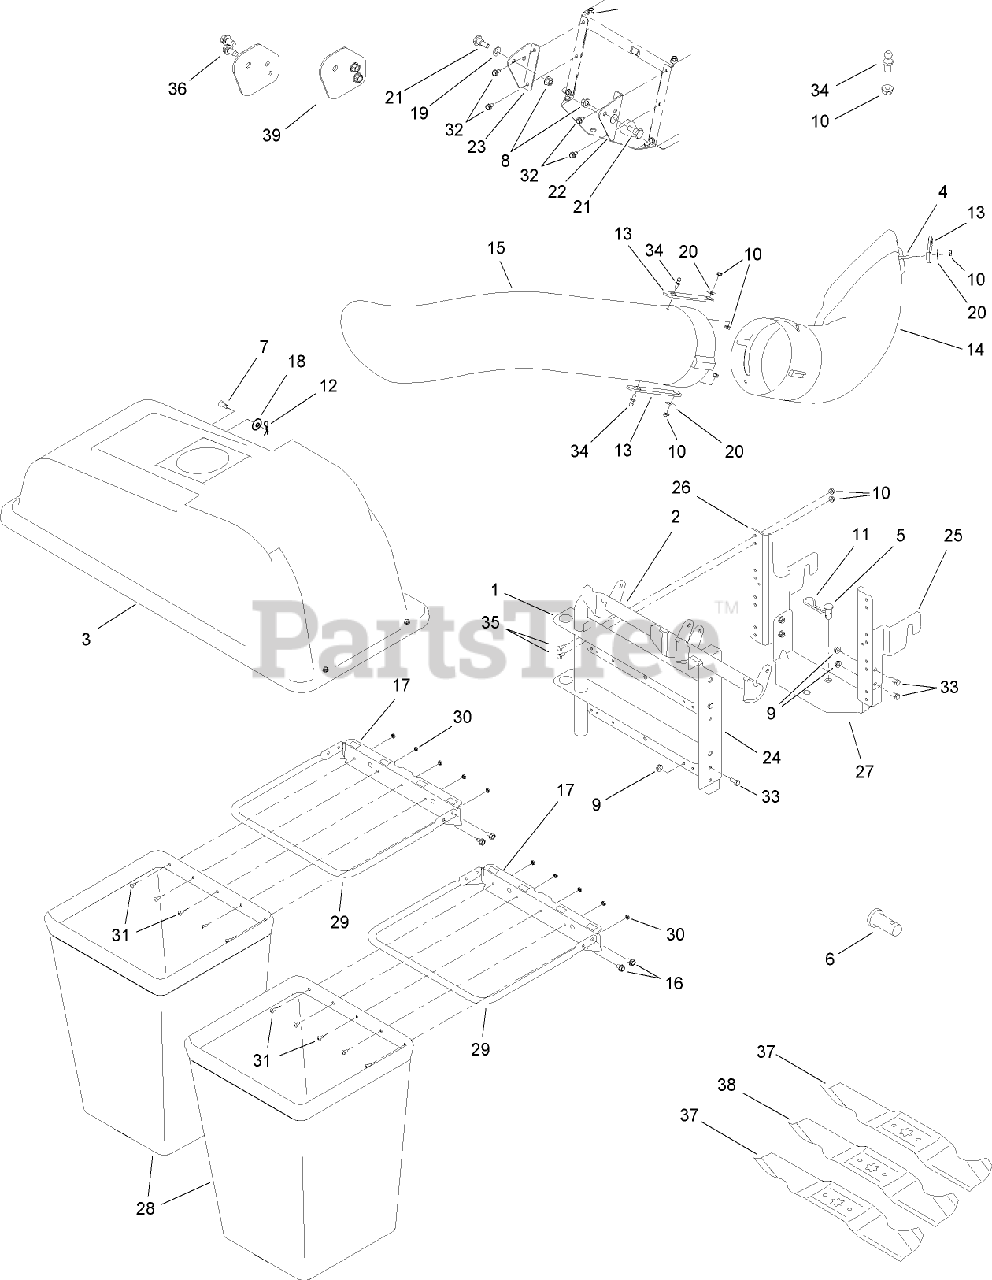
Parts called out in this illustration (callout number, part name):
1	BRACKET-MOUNTING
2	SUPPORT TUBE ASM
3	COVER ASM (DOUBLE)
4	SCREW-HH
5	PIN-CLEVIS
6	PIN-CLEVIS
7	PIN-CLEVIS
8	NUT-LOCK, FLANGE
9	NUT-LOCK, FLANGE
10	NUT-LOCK, FLANGE
11	CLIP-HAIRPIN
12	PIN-CLICK
13	STRAP-CHUTE
14	CHUTE-DISCHARGE
15	TUBE-ELBOW, CATCHER
16	SCREW-HWH
17	BRACKET-BAG, HANGER
18	WASHER-BELL
19	WASHER-BELL
20	WASHER-FLAT
21	BOLT-SHOULDER
22	BRACKET-SUPPORT, RH
23	BRACKET-SUPPORT, LH
24	BRACKET-SUPPORT
25	BRACKET-CATCHER, RH
26	BRACKET-CATCHER, LH
27	BRACKET-CROSS, SUPPORT
28	BAG-GRASS
29	FRAME-CATCHER, BAG
30	NUT-SEMS
31	SCREW-TRUSS, MACHINE
32	SCREW-HH, TAP
33	SCREW-HH
34	PIN-CATCHER, GRASS
35	SCREW-HH
36	SCREW-HWHTF
37	BLADE (2 IN 1 STAR, 16.28 INCH)
38	BLADE (2 IN 1 STAR, 14.88 INCH)
39	BRACKET-SUPPORT, CATCHER
